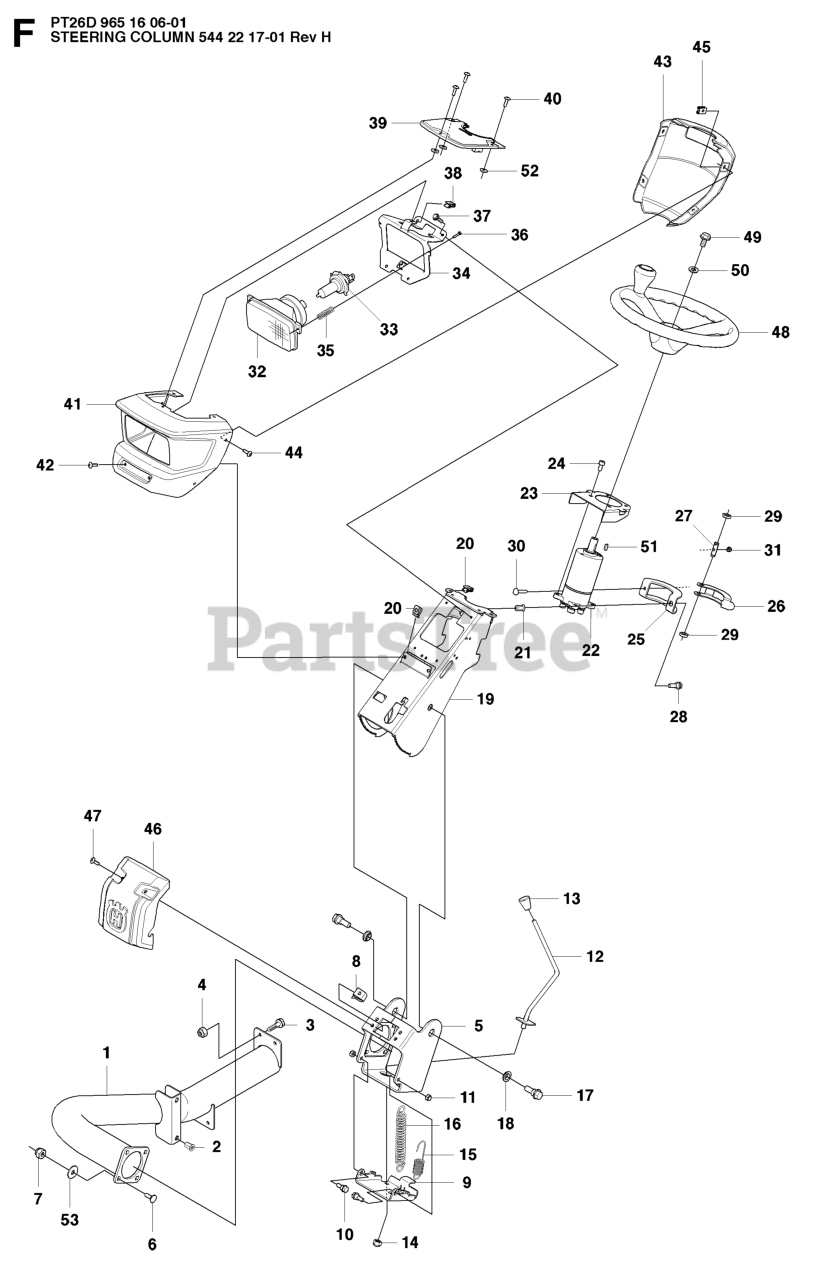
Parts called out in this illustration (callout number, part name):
4	LOCKNUT M8
7	LOCKNUT M8
11	LOCKNUT M8
16	DRAW SPRING L=108
21	BLIND RIVET NUT
31	LOCKNUT M6
49	SCREW EHHFM
53	WASHER BRB 8.4X17
